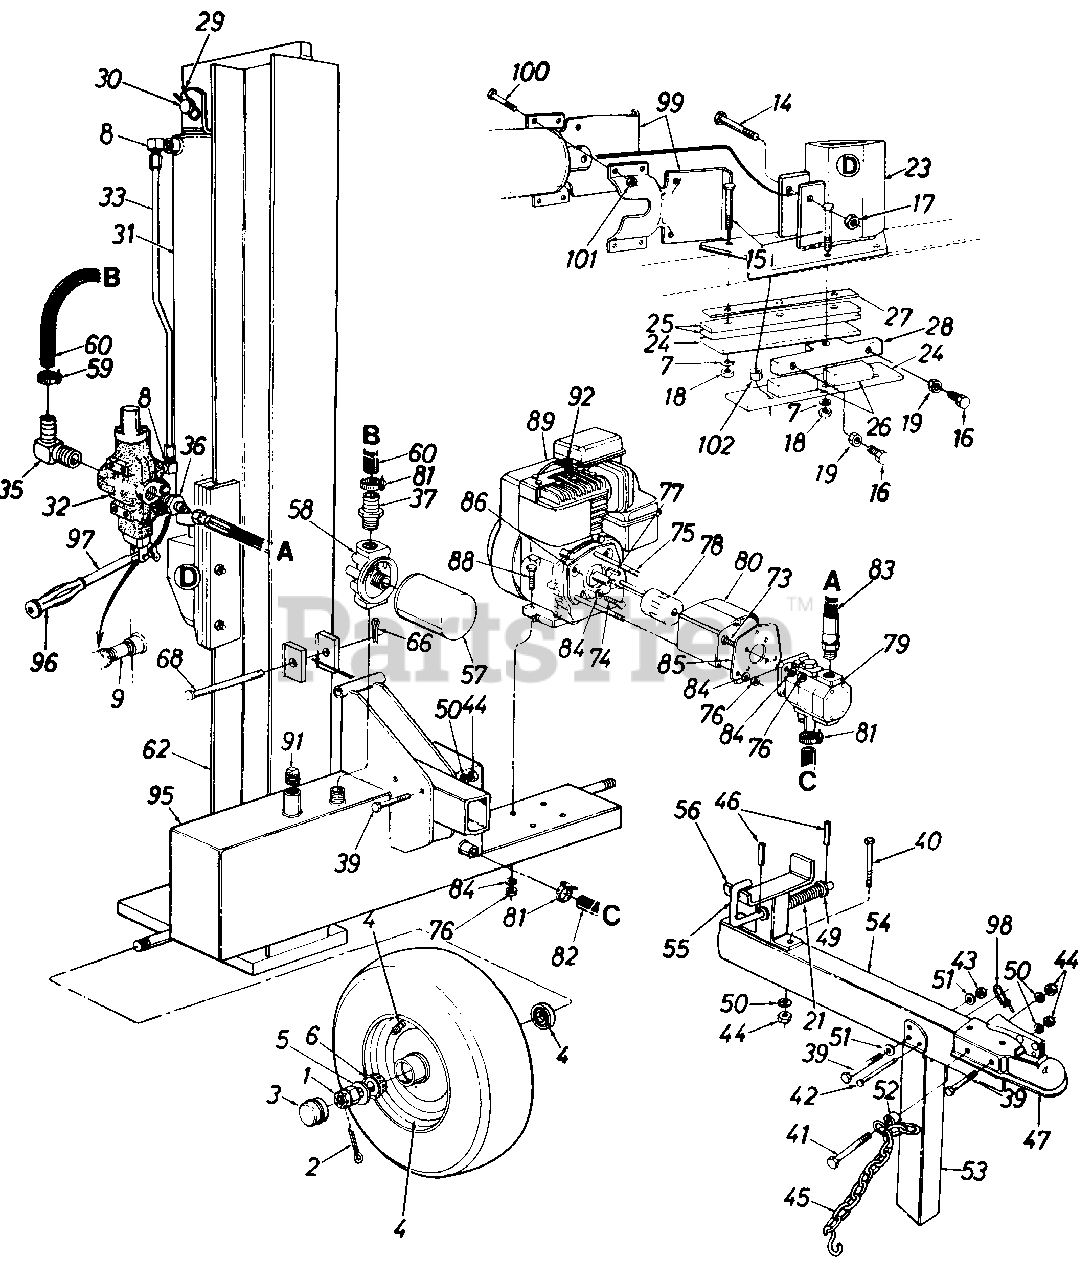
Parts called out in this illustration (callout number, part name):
1	Slotted Nut 3/4-16 Thd.
2	Cotter pin 5/32" Dia.
3	Hub Cap
5	Fl-Wash. .76" I.D. x 1.5" O.D.
6	Roller Bearing
7	L-Wash 1/2" I.D.
8	90ø Solid Male Adaptor
9	Pipe Nipple 1/2 NPT
14	Hex Bolt 1/2-20 x 3" Lg. (Grade 8)
15	Hex Bolt 1/2-20 x 2.75" Lg. (Grade 8)
16	Hex Bolt 3/8-24 x 1.5" Lg.
17	Hex L-Nut 1/2-20 Thd.
18	Hex Nut 1/2-20 Thd.
19	Hex Jam Nut 3/8-24 Thd. (Grade 5)
21	Comp. Spring 4" Lg.
29	External Cotter Pin
30	Cylinder Mounting Pin
31	Hydraulic Cylinder
33	Metal Pressure Tube
35	Return Elbow
36	Adapter
37	3/4 Hose Barb.
39	Hex Bolt 3/8-16 x 3" Lg. (Grade 8)
40	Hex Bolt 3/8-16 x 4" Lg.
41	Hex Bolt 3/8-16 x 3.25" Lg. (Grade 8)
42	Clevis Pin 5/16 x 2.5n Lg.
43	Hex L-Nut 3/8-16 Thd.
44	Hex Nut 3/8-16 Thd.
45	Chain-Tow Hitch
46	Roll Pin
47	Hitch Coupler
49	Fl-Wash. .635" I.D. x .93" O.D.
50	L-Wash. 3/8" I.D.
51	Fl-Wash. .406" I.D. x .75" O.D.
52	Spacer.27" Lg.
55	Locking Rod
57	Filter Element
58	Filter Head
59	Adj. Hose Clamp
60	Return Hose 3/4" I.D. x 44" Lg.
62	Vertical Beam Ass'y.
66	Cotter Pin 1/8" Dia.
68	Hinge Pin 1/2 x 4.8" Lg.
73	Hex Bolt 5/16-24 x 1 " Lg.
74	Hex Bolt 5/16-24 x .62" Lg.
75	Hex Bolt 5/16-24 x 5" Lg.
76	Hex Nut 5/16-24 Thd.
77	Sq.-Key 3/16" x .75"
78	Flexible Coupling
79	Two Volume Pump
80	Coupling Shield
81	Hose Clamp 5/8n
82	Suction Hose 3/4" I.D. x 17" Lg.
83	High Pressure Hydraulic Hose 62"
84	L-Wash. 5/16" I.D.
88	Hex Bolt 5/16-24 x 1.75" Lg.
89	Engine
91	L-Vent Pipe Plug
92	Spark Plug Boot
95	638/N Tank Ass'y.
96	Grip
97	Control Handle
98	Spring Pin
101	Hex L-Nut 3/8-16 Thd.
102	Spacer 1/2" I.D. x .68" Lg.
